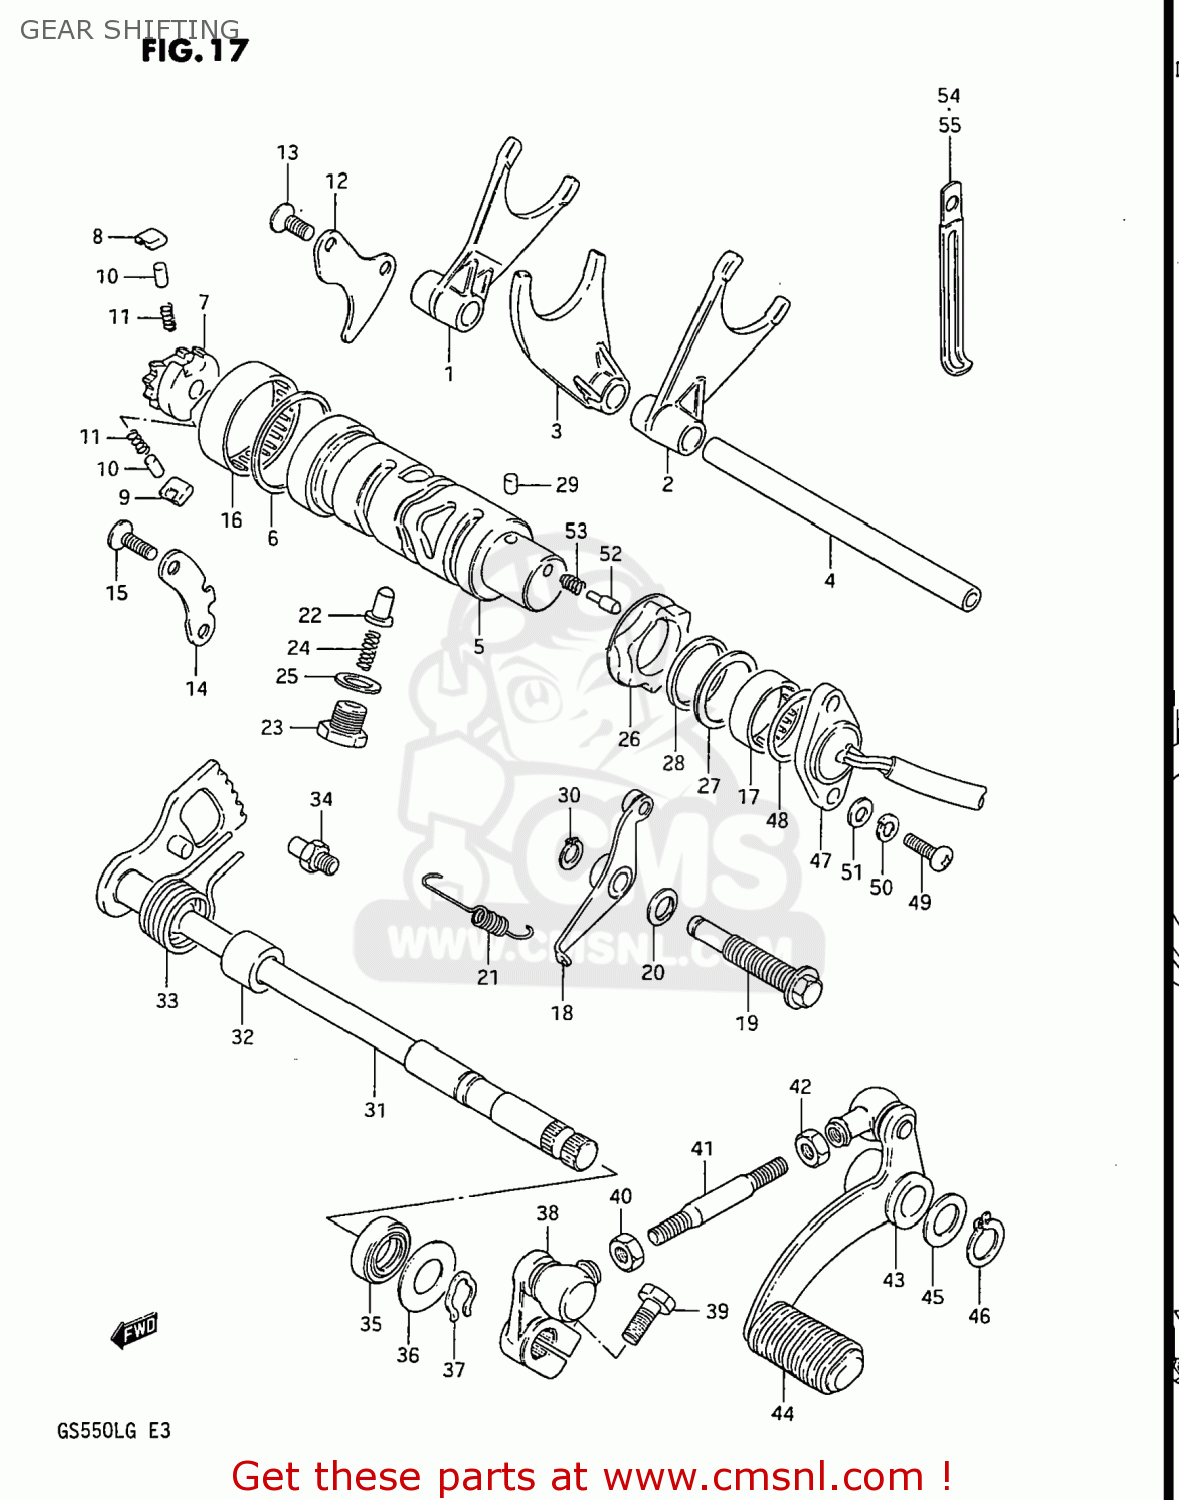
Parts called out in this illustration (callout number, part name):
1	FORK,GEAR SHIFT NO.1
2	FORK,GEAR SHIFT NO.2
3	FORK,GEAR SHIFT NO.3
4	SHAFT,GEAR SHIFT FORK
5	CAM,GEAR SHIFT
6	WASHER (40X49X1)
7	GEAR,GEARSHIFT CAM DRIVE
8	PAWL,GEAR SHIFT NO.1
9	PAWL,GEAR SHIFT NO.2
10	PIN(5X8)
11	SPRING
12	LIFTER,GEAR SHIFT PAWL
13	SCREW
14	GUIDE,GEAR SHIFT CAM
15	SCREW
16	BEARING(43X49X12)
17	BEARING(25X32X12)
18	STOPPER,GEAR SHIFTING
19	HOLDER,SHIFTING CAM STOPPER
20	GASKET(10X14X3.6) (NAS)
21	SPRING
22	STOPPER,GEAR SHIFTING
23	HOLDER,GEAR SHIFT CAM STOP SPR
24	SPRING
25	GASKET(14X19.2X2) (NAS)
26	PLATE,GEAR SHIFT CAM STOPPER
27	WASHER
28	WASHER
29	PIN 4X6
30	CIRCLIP
31	SHAFT,GEAR SHIFT
32	SPACER(12X20X15.3)
33	SPRING
34	STOPPER,GEAR SHIFT CAM
35	OIL SEAL
36	WASHER (12.5X27X1.6)
37	SPRING,RETAINER
38	ARM,GEAR SHIFT LINK
39	BOLT
40	NUT
41	ROD,GEAR SHIFT LINK
42	NUT
43	LEVER ASSEMBLY,GEAR SHIFTING
44	RUBBER,PEDAL
45	WASHER(12.5X20X1)
46	CIRCLIP
47	SWITCH ASSEMBLY,GEAR SHIFT
48	O-RING (D:2.4 ID:26.2)
49	SCREW(5X14)
50	LOCK WASHER
51	WASHER
52	PIN(5X15.5)
53	SPRING
54	CLAMP L:35
55	CLAMP
